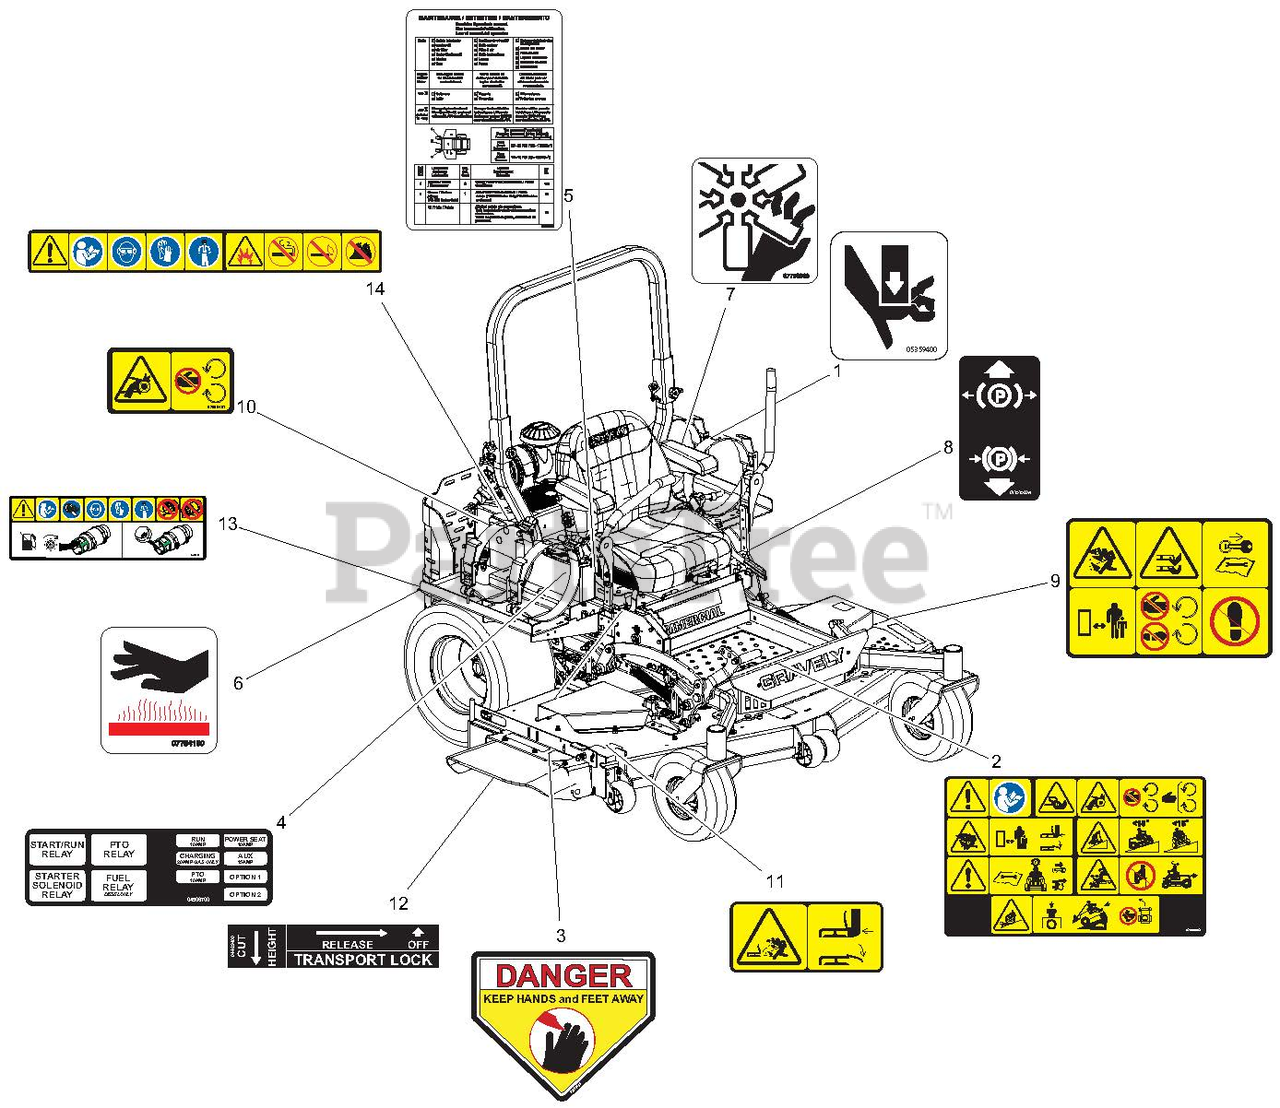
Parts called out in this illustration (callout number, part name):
1	DECAL, PINCH POINT
2	DECAL, MAIN SAFETY, COMMERCIAL
3	DECAL, DANGER
4	DECAL, FUSE BOX
5	DECAL, MAINTENANCE
6	DECAL, HOT SURFACE
7	DECAL, DANGER - FAN
8	DECAL, PARKING BRAKE LEVER
9	DECAL, SAFETY - MOWER DECK
10	DECAL, SAFETY - GUARDING
11	DECAL, SAFETY - DECK GUARDING
12	DECAL, TRANSPORT LOCK INSTRUCTION
13	DECAL, HORZ. MOWER TANKS ONLY
14	DECAL, SAFETY- LP
